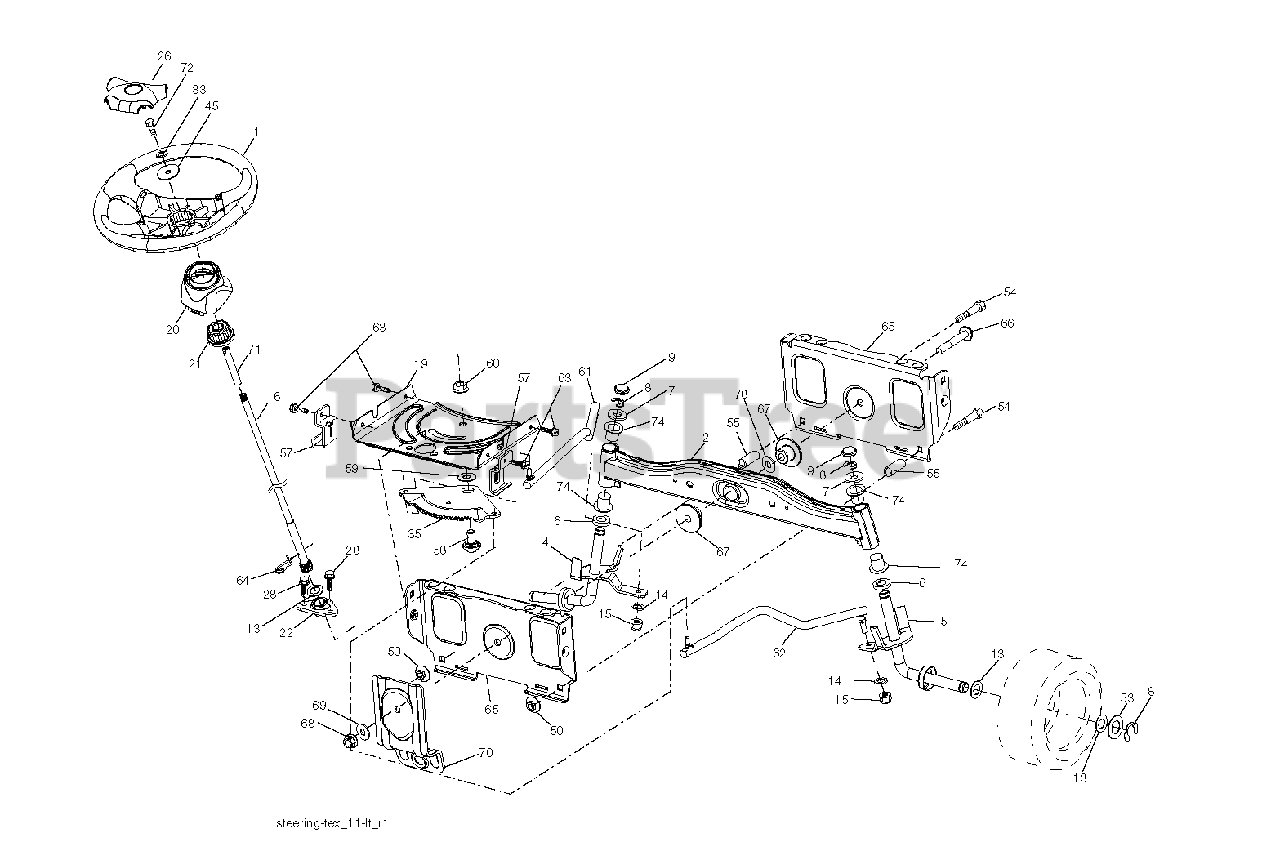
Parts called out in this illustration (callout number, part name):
1	WHEEL.STEERING.STDSRR.BLK/OV
2	AXLE HALF ASM-WELDED
4	SPINDLE.WELDED.LH.15"TEX
5	SPINDLE.WELDED.RH.15"T
8	RING CLIP
9	CAP.SPINDLE.BLACK
14	WASHER, LOCK 3/8
15	NUT CROWNLOCK 3/8-24
16	SHAFT STEERING
19	PLATE.STEER.DDL.NLT/NG
20	BOOT STEERING BLACK
21	ADAPTER, WHEEL STNG..
22	BUSHING.ASM.STEERING.A
26	INSERT, WHEEL STEERING
28	SCREW, 3/8-16X3/4
33	LOCKWASHER
35	GEAR.SECTOR.PLATE.DDL.
45	WASHER.11/32
50	NUT LOCK FLG 3/8-16 UNC
53	WASHER.HARDENED
55	SPACER.BRACE.AXLE
57	BRACKET.UPSTOP.TEX
58	BOLT.SHOULDER.SECTOR.P
59	WASHER.THURST.SECTOR.S
60	NUT FLANGE LOCK 5/8-11
61	DRAGLINK.LH.BALLSTUD.D
62	DRAGLINK.RH.BALLSTUD.D
63	SCREW
64	RETAINER.CLIP.SPRING.S
65	BRACE.AXLE.FRONT.NLT/N
66	BOLT HEX FGHD 7/16-14 X 3 SERR
67	BUSHING.PM.FRONT AXLE
68	NUT.LOCK.FLANGE.7/16
69	WASHER.1.5X.505X.118
70	BRKT.DECK.SUSPENSION.F
71	SHAFT EXTENSION STEERING
72	BOLT YT
74	Steering Column Bearing
78	THRUST WASHER
